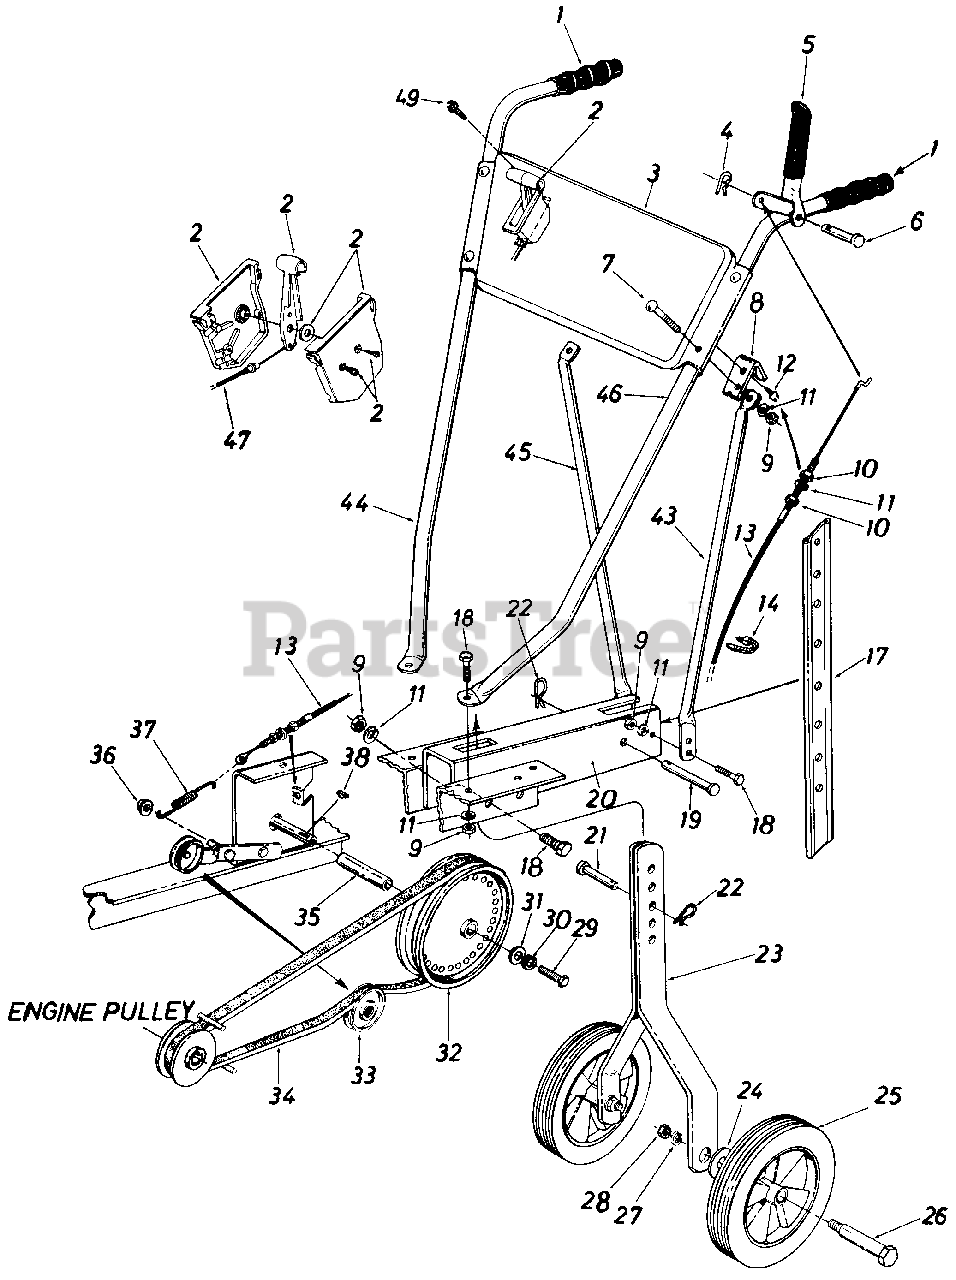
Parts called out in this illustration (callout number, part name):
2	Throttle Control Box
3	483Handle Panel
4	Int. Cotter Pin
5	Clutch Grip Ass'y.
7	Carriage Bolt 5/16-18 x 1.75" Lg.
8	Cable Support Brkt.
9	Hex Nut 5/16-18 Thd.
10	Hex Jam Nut 5/16-24 Thd.
11	L-Wash 5/16" I.D.
12	Hex Wash. Hd. Self-Tap Scr. 1/4-20 x .50" Lg.
13	Clutch Control Cable
18	Hex Bolt 5/16-18 x .75" Lg.
19	Clevis Pin 1/2" Dia. x 2.50" Lg.
20	Tailpiece Ass'y.
21	Clevis Pin 818" Dia. x 2.50" Lg.
22	Hairpin Cotter
23	Wheel Bracket Ass'y.
24	Belleville Wash. 1/2" I.D.
25	Wheel Ass'y. Comp.-Steel
26	Shoulder Bolt
27	L-Wash. 1/2" l.D.
28	Hex Nut 1/2-20 Thd.
29	Hex Bolt 1/4-28 x 75" Lg.
30	L-Wash. 1/4" l.D.
31	Fl-Wash. .25" I.D. x .930" O.D.
32	Pulley 6.00" O.D.
33	Idler Pulley
34	"V"-Belt 1/2" Pitch x 39" Lg.
36	Cap Speed Nut
37	Extension Spring
38	Hi-Pro Key
43	Handle Support Bracket-L.H.
44	Handle Bar-R.H.
45	Handle Support Bracket-R.H.
46	Handle Bar-L.H.
47	Throttle Control Cable 35"
49	Self-Tap Scr. #10 x 1/2" Lg.
